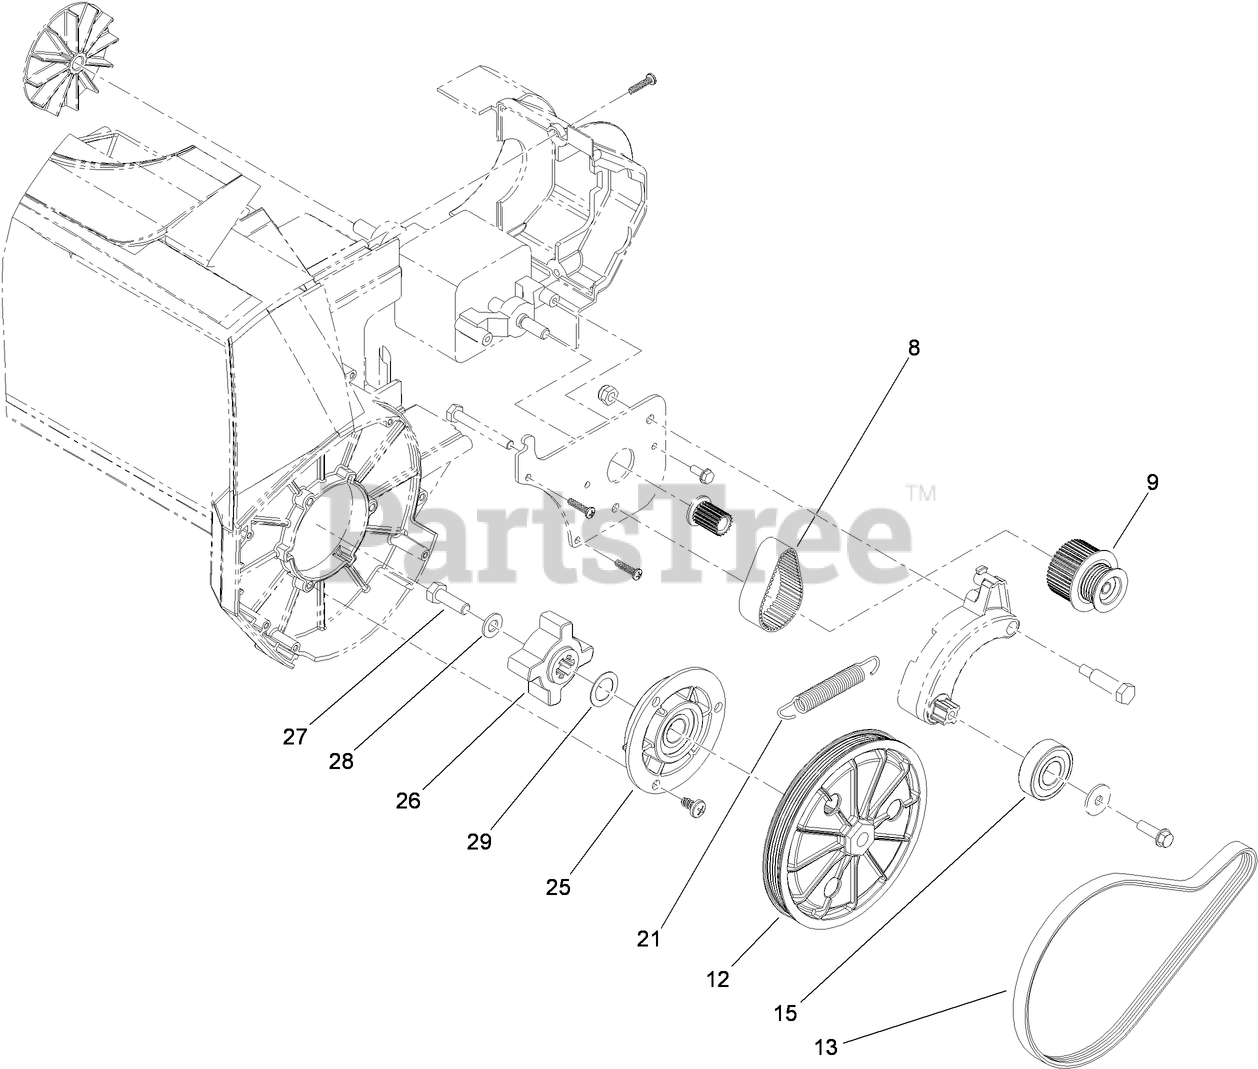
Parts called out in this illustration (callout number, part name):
8	BELT-PULLEY, IDLER/DRIVER
9	IDLER PULLEY ASM
12	PULLEY ASM
13	BELT-DRIVE
15	BEARING-BALL
21	SPRING-IDLER
25	PILLOW BLOCK ASM
26	COUPLER-PULLEY
29	WASHER-PLAIN
